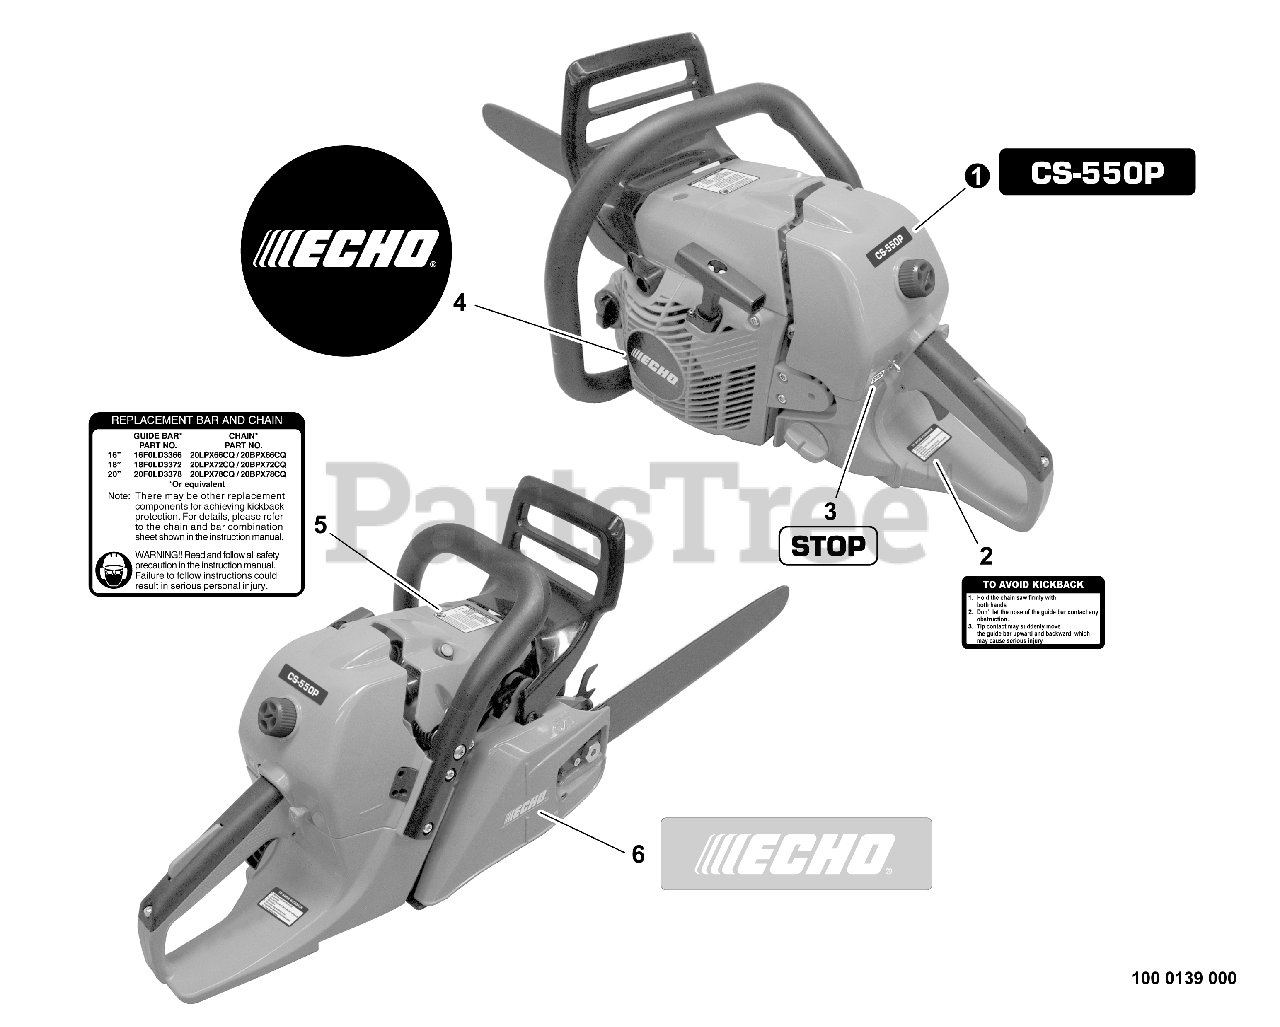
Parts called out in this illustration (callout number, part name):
1	LABEL - MODEL CS-550P
2	LABEL - KICK BACK
3	LABEL - STOP
4	LABEL - ECHO
5	LABEL - BAR & CHAIN
6	LABEL - ECHO
